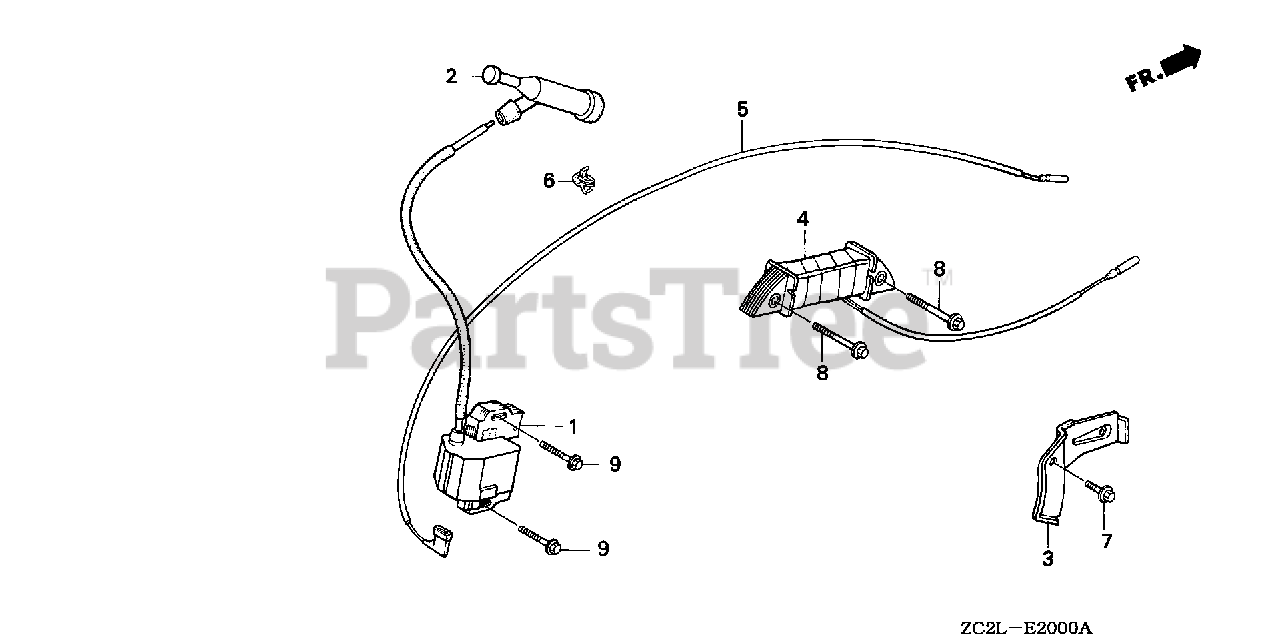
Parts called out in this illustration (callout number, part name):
1	COIL ASSY., IGNITION
2	CAP ASSY., NOISE SUPPRESSOR (NICHIWA Y-EZ RTFM256)
5	WIRE, STOP SWITCH (430MM)
9	BOLT, FLANGE (6X28) (CT200)
